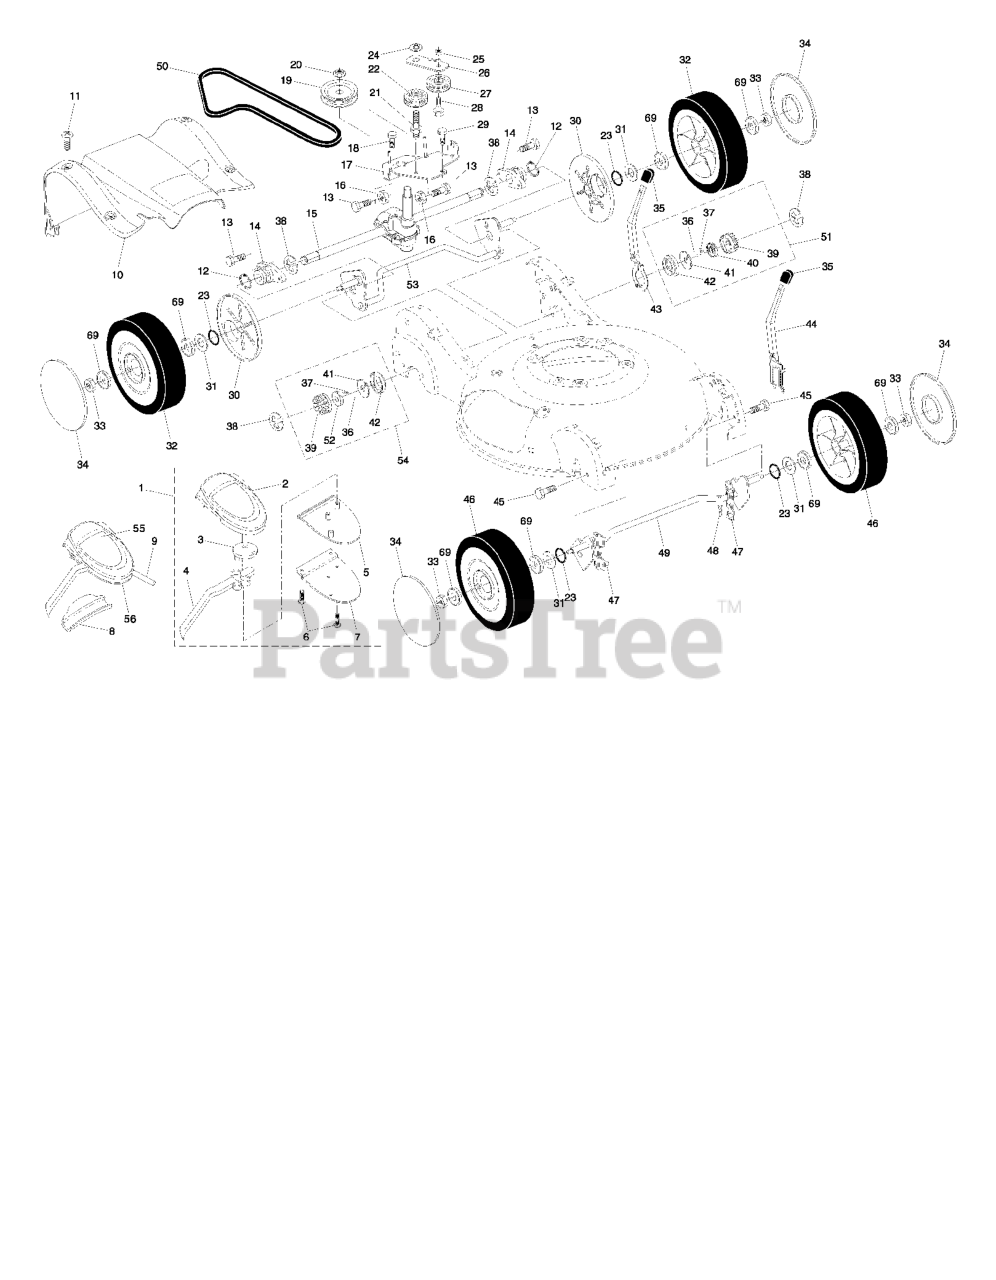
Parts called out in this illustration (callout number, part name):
1	EZ WALK CONTROL
2	COVER, DRIVE CONTROL, TOP
3	PULLEY.CAM.DRIVE.CONTROL.HV
4	LEVER, DRIVE CONTROL
5	COVER, DRIVE CONTROL BOTTOM
6	SCREW, PHILLIPS HEAD 10 X 5/8
7	BRACKET, DRIVE CONTROL
8	EZ WALK SNAP COVER PLATE
9	CABLE, DRIVE CONTROL
10	COVER ASM. DRIVE
11	SCREW
12	RETAINING RING (2 2)(3 2)
13	RP SCREW
14	BEARING.SUPPORT.ASSEM
15	TRANSMISSION.ASM.RGD.EZ.21
16	NUT
17	BRACKET, TRANSMISSION
18	Screw, Hex Washer Head #10-24 x .668
19	PULLEY HALVES
20	FLANGED LOCKNUT 3/8-16 ZINC
21	BOLT, IDLER
22	PULLEY ASSY
23	O-RING
24	NUT
25	NUT.CENTERLOCK.5/16-
26	BRACKET
27	IDLER PULLEY
28	SHOULDER BOLT
29	SCREW 14-20 X 5/8
30	DUST COVER, WHEEL
31	WASHER.FLAT.1/2
32	WHEEL ASM, REAR 9 X 2-1/4
33	HEX FLANGE LOCKNT
34	RB HUBCAP.3-SPOKE.SILVER
35	KNOB.SELECTOR.SPRG.H-GRY (2 2)
36	SPRING, TORSION
37	PAWL.DRIVE.21.EZ-WALK
38	E-RING 7/16 RE
39	GEAR, PINION
40	RETAINER.DRIVE.21.EZ-WALK.LT
41	DISC.DRIVE.21.EZ-WALK
42	SEAL.PINION
43	LEVER, SELECTOR, HEIGHT, REAR
44	LEVER, SELECTOR, HEIGHT, FRONT
45	SCREW
46	WHEEL
47	BUSHING.FRONT.TORQUE.SHAFT
48	SPRING RETAINER
49	TORQUE SHAFT ASSY
50	BELT.DRIVE.EZ.WALK.HI-VAC
51	PINION ASSY, LH
52	RETAINER, DRIVE, RH
53	REAR AXLE ASSY.
54	PINION ASSY, RH
55	DECAL.DRIVE.CONTROL.HV
56	DECAL
69	BEARING.8".WHEEL
